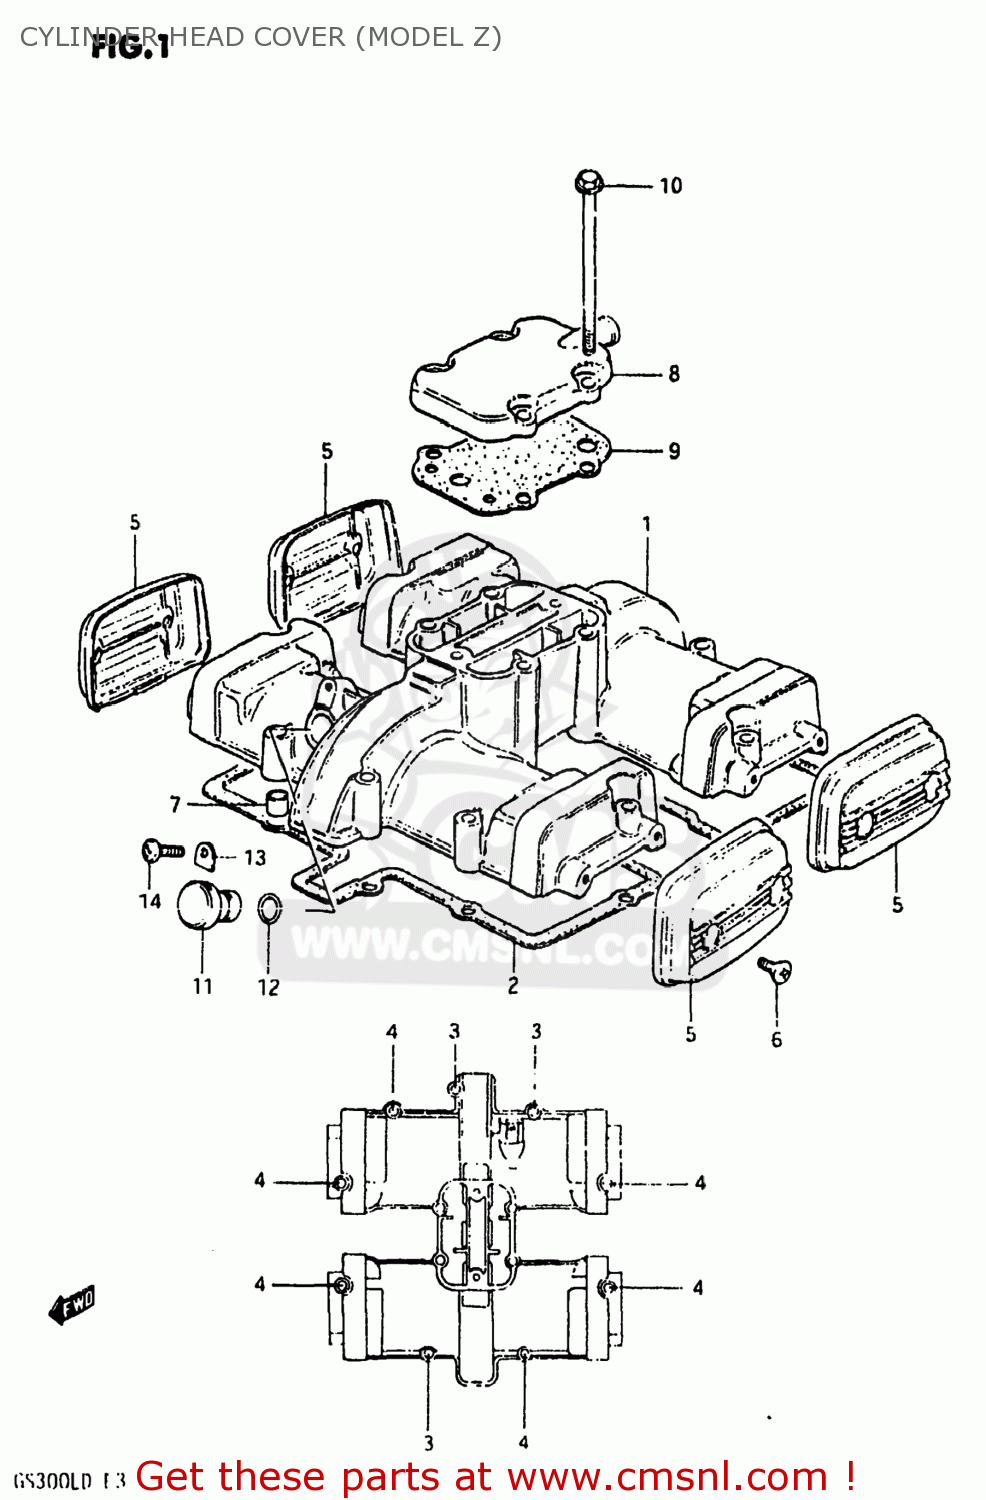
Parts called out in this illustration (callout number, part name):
1	COVER,CYLINDER HEAD
2	GASKET,CYLINDER HEAD COVER ( (MCA)
3	BOLT
4	BOLT 6X35
5	CAP,CYLINDER HEAD COVER
6	SCREW(5X12)
7	PIN(6.2X8X11)
8	COVER,BREATHER
9	GASKET,BREATHER COVER (MCA)
10	BOLT (6X75)
11	PLUG,TACH GEAR SLEEVE HOLE
12	SEAL,TACHOMETER DRIVEN
13	PLATE,TACH DRIVE GEAR SLEEVE
14	SCREW(5X12)
